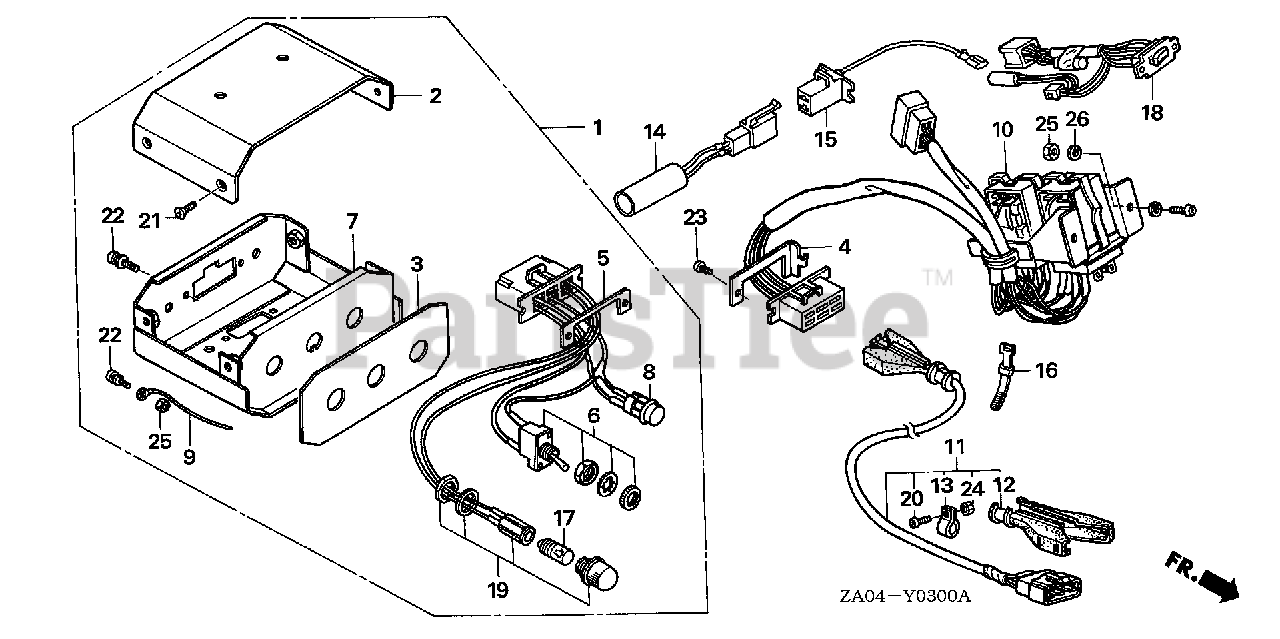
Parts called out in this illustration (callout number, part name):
1	BOX ASSY., SWITCH *R8* (BRIGHT RED)
2	COVER (UPPER)
3	PANEL, FR.
4	HOLDER, CONNECTOR (6P)
5	PLATE, CONNECTOR SETTING
6	SWITCH, TOGGLE
7	CASE, SWITCH
8	SWITCH, PUSH
9	WIRE, GROUND
10	RELAY ASSY.
11	CABLE, REMOTE CONTROL (10M)
12	COVER, CONNECTOR
13	BAND
16	BAND B1, WIRE
17	BULB, DASH (24V-2W)
19	SOCKET ASSY., PILOT LAMP
19	HOLDER, LAMP
20	SCREW, PAN (3X12)
21	SCREW, FLAT (4X8)
22	SCREW-WASHER (4X12)
23	SCREW, TAPPING (4X10)
24	NUT, HEX. (3MM)
25	NUT, HEX. (4MM)
26	WASHER, SPRING (4MM)
